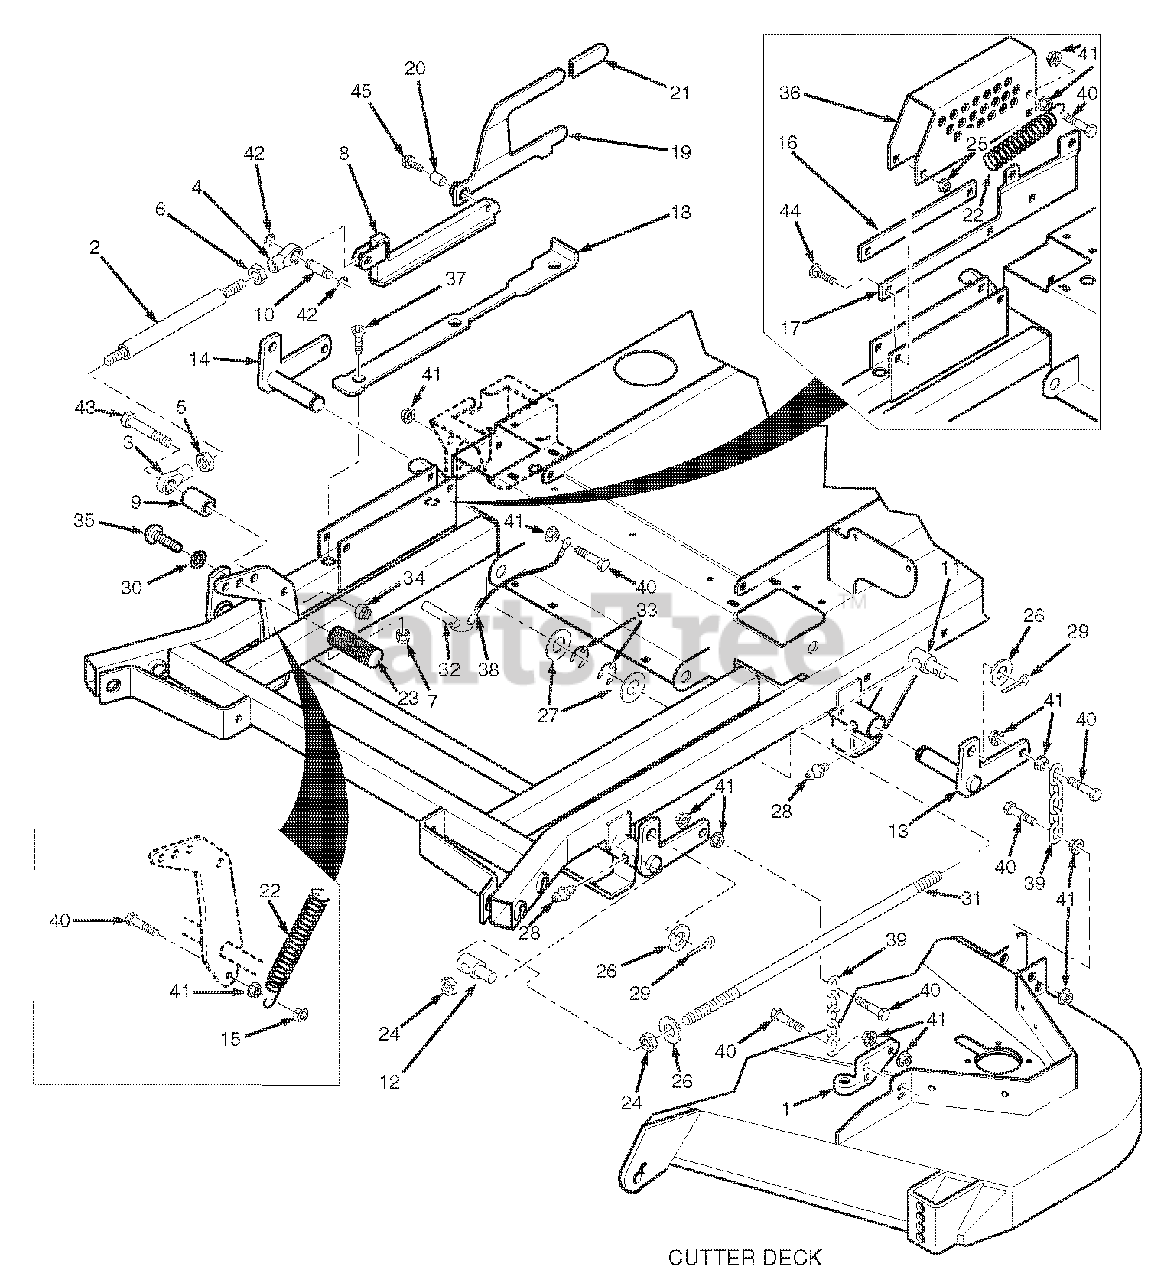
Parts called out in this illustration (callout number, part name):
1	Lever Assembly, Deck Level
2	Link, Deck Lift
3	Rod End, Female - 1/2-20 RH
4	Rod End, Female - 1/2-20 LH
5	Nut, Jam 1/2-20 RH
6	Nut, Jam 1/2-20 LH
7	Nut, 3/8-16 Elastic Stop
8	Slide Weldment, Height Adjustment
9	Spacer, Decklift Pedal
10	Pin, Decklift
11	Swivel Joint, LH
12	Swivel Joint, RH
13	Bellcrank Weldment, LH Rear
14	Bellcrank Weldment, RH Rear
15	Locknut, 3/8-16 Center Lock
16	Guide, Short
17	Guide, Long
18	Lockplate, Decklift
19	Deck Latch
20	Bushing, .502" ID.
21	Grip, Deck Latch
22	Spring, Helper (61" & 72" Cutter Decks Only)
23	Foot Pedal, Height Adjustment
24	Nut, Hex 5/8-11
25	Nut, Hex Serrated Flange 5/16-18
26	Flatwasher, 5/8" (.656 x 1.312 x .095")
27	Flatwasher, 1" (1.062 x 1.50 x .048")
28	Grease Fitting
29	Cotter Pin, 3/16 x 1"
30	Lockwasher, 5/8"
31	Stud, 5/8-11 x 22.0"
32	Ring Pin, 1/2 x 3.06"
33	Ring, Retaining 1" External "E"
34	Nut, Hex Elastic Stop 1/2-13
35	Capscrew, 5/8-11 x 1-1/2"
36	Bracket, Cutting Height Adjustment
37	Screw, Cap 5/16-18 x 3" FHHS
38	Lanyard, Deck Height Pin
39	Chain
40	Bolt, Hex Head 3/8-16 x 1-1/2"
41	Nut, Hex Serrated Flange 3/8-16
42	Ring, Retaining 1/2" External "E"
43	Bolt, Hex Head 1/2-13 x 3"
44	Bolt, Carriage 5/16-18 x 1"
45	Bolt, Shoulder 1/2 x 3/4"
